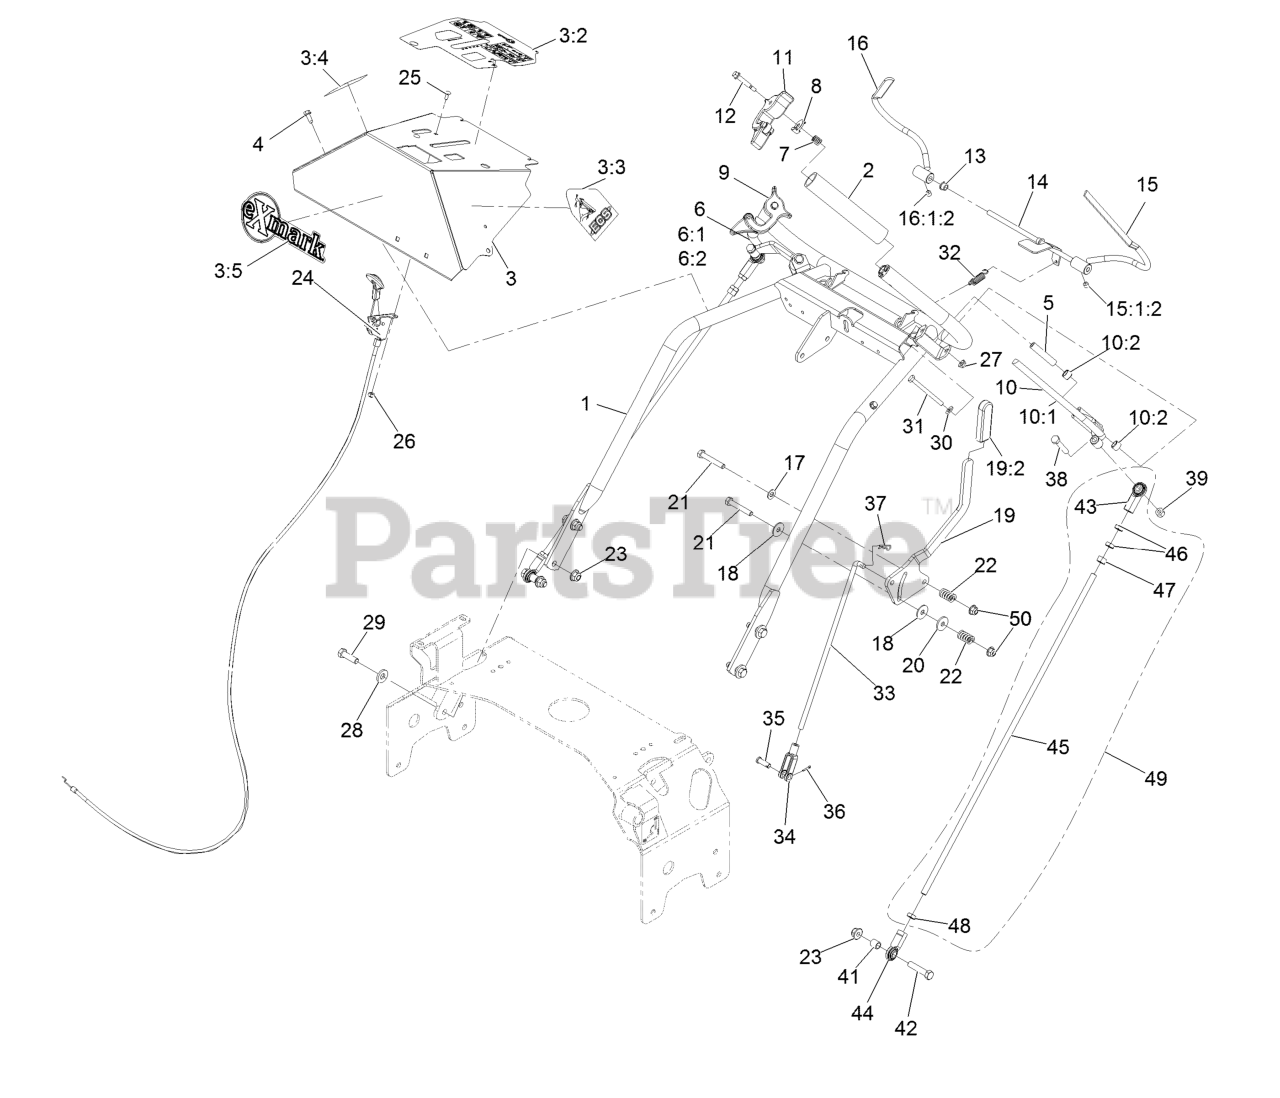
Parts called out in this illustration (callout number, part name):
1	Weld, Handle
2	Grip-Bar, Handle
3	ASM, Console W/ Decals
3:2	Decal-Console
3:3	Decal, Ecs Instruction LH
3:4	Decal, Ecs Instruction RH
3:5	Decal, Exmark Logo
4	Screw-HWH 1/4-20 X .62
5	Bushing-Lever, Drive
6	Asm, Drive Lever RH
6:1	Wld,RH Drive Lever
6:2	Bushing, Sleeve
7	Spring-Compression
8	Latch, Ecs
9	Thumb Latch Asm RH
10	Asm, Drive Lever LH
10:1	Wld,LH Drive Lever
10:2	Bushing, Sleeve
11	Thumb Latch Asm LH
12	Screw-Shoulder
13	Bushing-Nylon
14	Rod Weldment, OPC
15	Wld,LH OPC Lever
15:1:2	Setscrew-5/16-24 X 5/16
16	Wld,RH OPC Lever
16:1:2	Setscrew-5/16-24 X 5/16
17	Washer-5/16 SAE
18	Washer-Friction
19	Lever, Shift W/Grip
19:2	Grip-Handle, Steering
20	Washer-Friction Disc
21	Screw-HH 5/16-18 X 2 1/4
22	Spring-Compression
23	Nut-Nyloc 3/8-16 Flg
24	Control-Throttle
25	Bolt-Carriage #10-24 X 1/2
26	Nut-Nyloc #10-24
27	Nut-Nyloc 1/4-20 Flg
28	Washer-Spring Disc 3/8
29	Screw-HH 3/8-16 X 1 1/4
30	Washer-1/4 SAE
31	Screw-HH 1/4-20 X 2 3/4
32	Spring-Extension
33	Rod, Speed Control
34	Yoke-Adjustable
35	Pin-Clevis 5/16 X 1 49/64
36	Pin-Cotter 3/32 X 1/2
37	Hairpin-Cotter
38	Screw-HH 5/16-18 X 1 3/4
39	Nut-Nyloc 5/16-18
41	Spacer-Tube, Pump Link
42	Screw-HH 3/8-16 X 1 3/4
43	Balljoint
44	Joint-Ball End
45	Rod,Drive Lever
46	Nut-Jam 3/8-24
47	Nut-Hex 3/8-24
48	Nut-Jam 3/8-24 LH
49	Drive Link ASM
50	Nut-Nyloc 5/16-18 Flg
